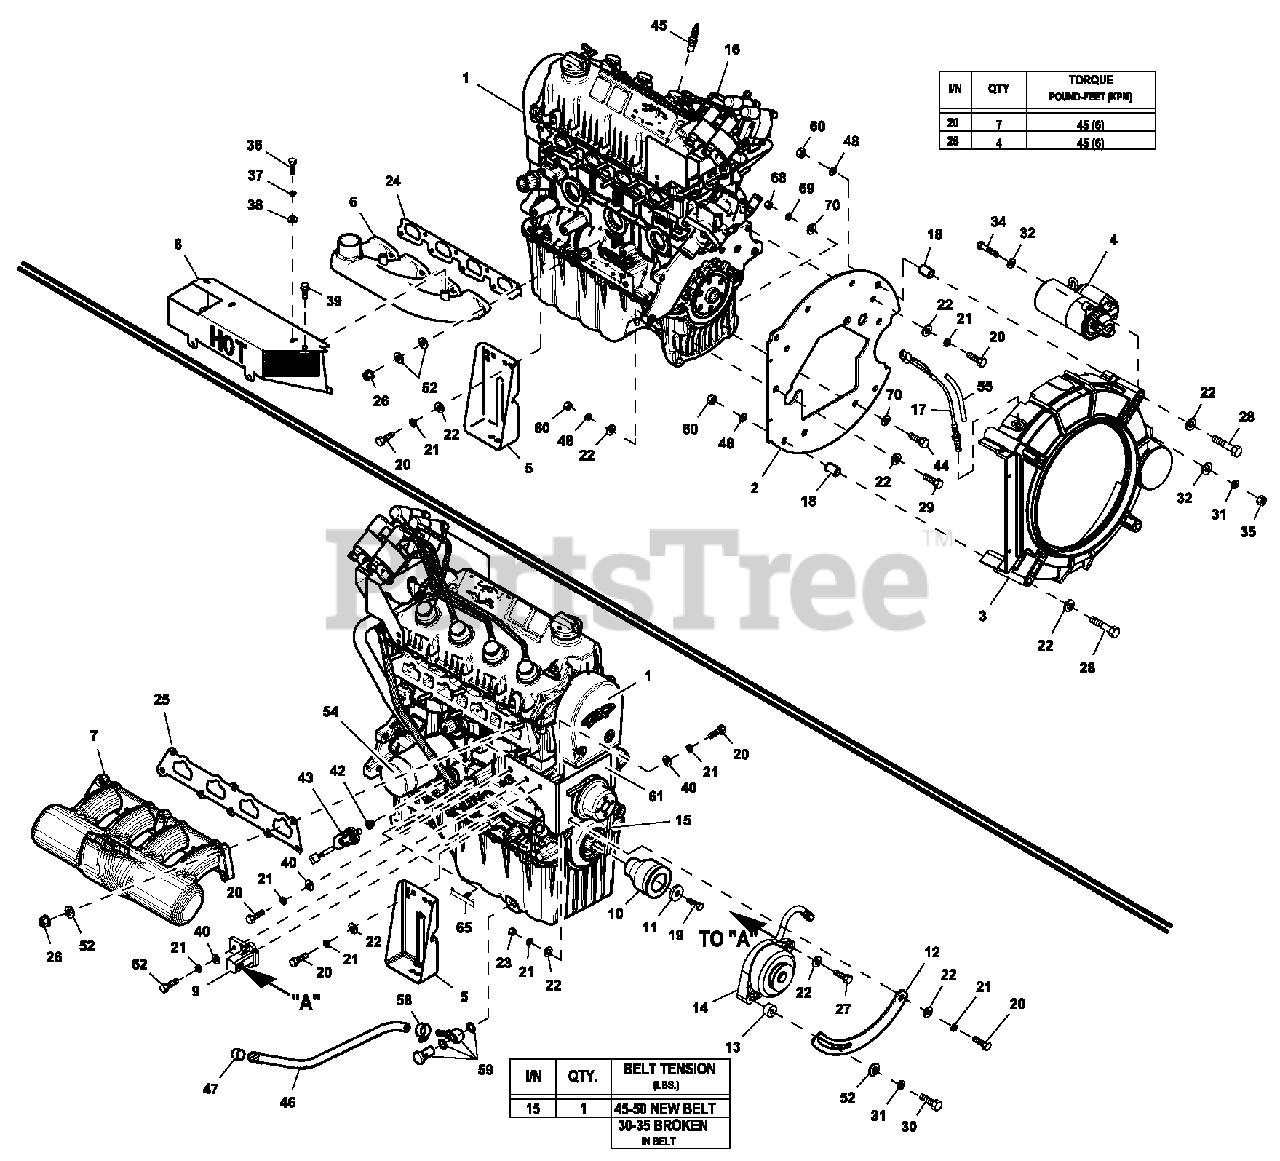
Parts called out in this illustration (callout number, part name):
1	ENGINE GENERAC 1.5LG11 CERT
2	ENGINE PLATE 1.5L 6MM
3	HOUSING BLOWER LG PILOT
4	STARTER MOTOR 12V
5	ENGINE MOUNTING FOOT STAMPING
6	EXHAUST MANIFOLD 1.6L MACHINED
7	INTAKE MANIFOLD MACH 1.5L G11
8	SHIELD 1.6L EXHAUST HEAT
9	DC ALTERNATOR ADAPTER MACHINED
10	PULLEY CRANKSHAFT MACHINED
11	WASHER PULLEY
12	BRACKET TENSIONER DC ALT
13	SPACER ALTERNATOR
14	DC ALTERNATR HAN-KOK
15	V-BELT 3/8X30.6
16	SPARK PLUG WIRE SET 1.5LG11
17	ASSY MAGPICKUP (3/8-24 MALE)
18	BUSHING GUIDE 19.3MM LONG
19	SCREW HHC M12-1.5X 40 G10.9
20	SCREW HHC M10-1.5X 25 G10.9
21	WASHER LOCK M10
22	WASHER FLAT 3/8-M10 ZINC
23	NUT HEX M10-1.5 CLASS 10 ZINC
24	GASKET, EXHAUST MANIFOLD
25	GASKET INTAKE MANIFOLD G11
26	NUT TOP LOCK FL M8-1.25
27	SCREW HHC M10-1.5X70 G8.8
28	SCREW HHC M10-1.25 X 100 PC8.8
29	SCREW HHC M10-1.25X45 C8.8
30	SCREW HHC M8-1.25X35 G8.8
31	WASHER LOCK M8-5/16
32	WASHER FLAT 5/16-M8ZINC
34	SCREW HHC M8-1.25X 40 G8.8
35	NUT HEX M8-1.25 G8 CLEAR ZINC
36	SCREW HHC 1/4-20 X 1/2 G5
37	WASHER LOCK M6-1/4
38	WASHER FLAT 1/4-M6 ZINC
39	SCREW HWHTF M6-1.0 X 16
40	WASHER FLAT M10 HEAVY DUTY
42	BSHG RDCR HEX 1/4 TO 1/8
43	HARN LOW OIL PRESS SWITCH ASSY
44	SCREW HHC M12-1.75 X55 C10.9
45	SPARK PLUG
46	HOSE OIL DRAIN ASSY 21"
47	CAP HEX 1/4 NPT BRASS
48	WASHER LOCK M10 RIBBED ZINC
52	WASHER FLAT .34IDX.75OD
54	OIL FILTER 1.6,2.5,3.0,4.2L G3
55	CONDUIT FLEX .25"ID (6" LG)
58	CLAMP HOSE .38- 87
59	BANJO ASSY M16-1.0
60	NUT HEX M10-1.25 G8 YELCHR
61	BRACKET FAN ALT ADAPTER 1.6L
62	SCREW HHC M10-1.5X35 G8.8
65	ANCHOR HARNESS
68	NUT HEX M12-1.75 G8 YELCHR
69	WASHER LOCK M12
70	WASHER FLAT M12
